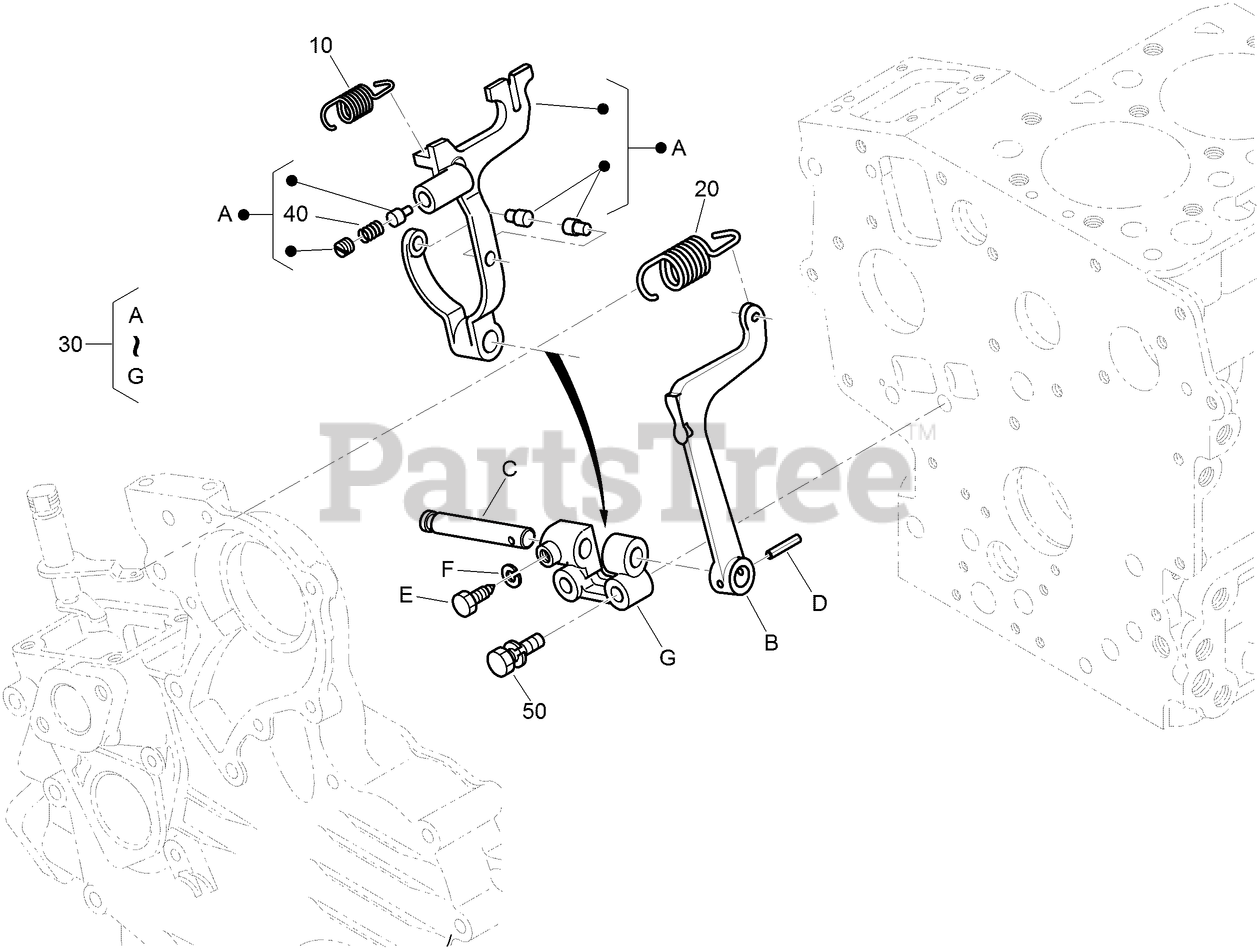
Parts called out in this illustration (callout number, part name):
10	SPRING-START
20	SPRING-GOVERNOR
30	FORK LEVER ASM
40	SPRING
